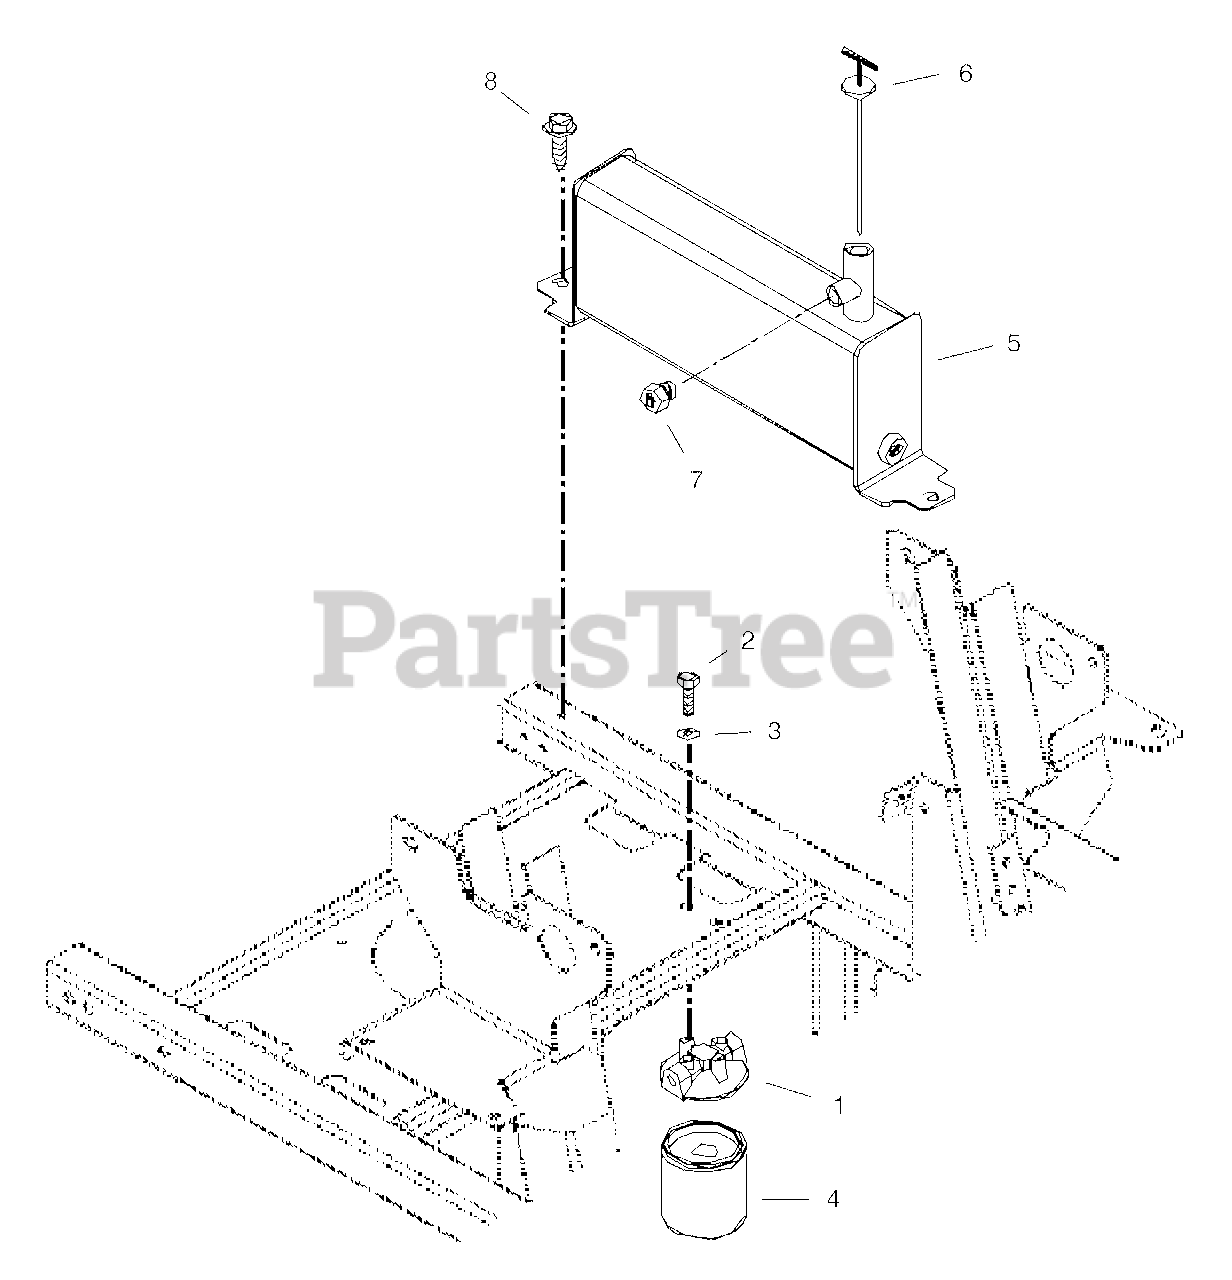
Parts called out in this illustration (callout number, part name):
1	Head-Filter
2	Bolt-Hex .25-20 x .75 Grade 5
3	Washer-Locking .25 x .062
4	Oil Filter
5	Tank-Hydraulic Weldment
6	Hydraulic Tank Dipstick
7	Plug-Breather .38
8	Screw-Tapping .38-16 x .75 Hex Washer Head
